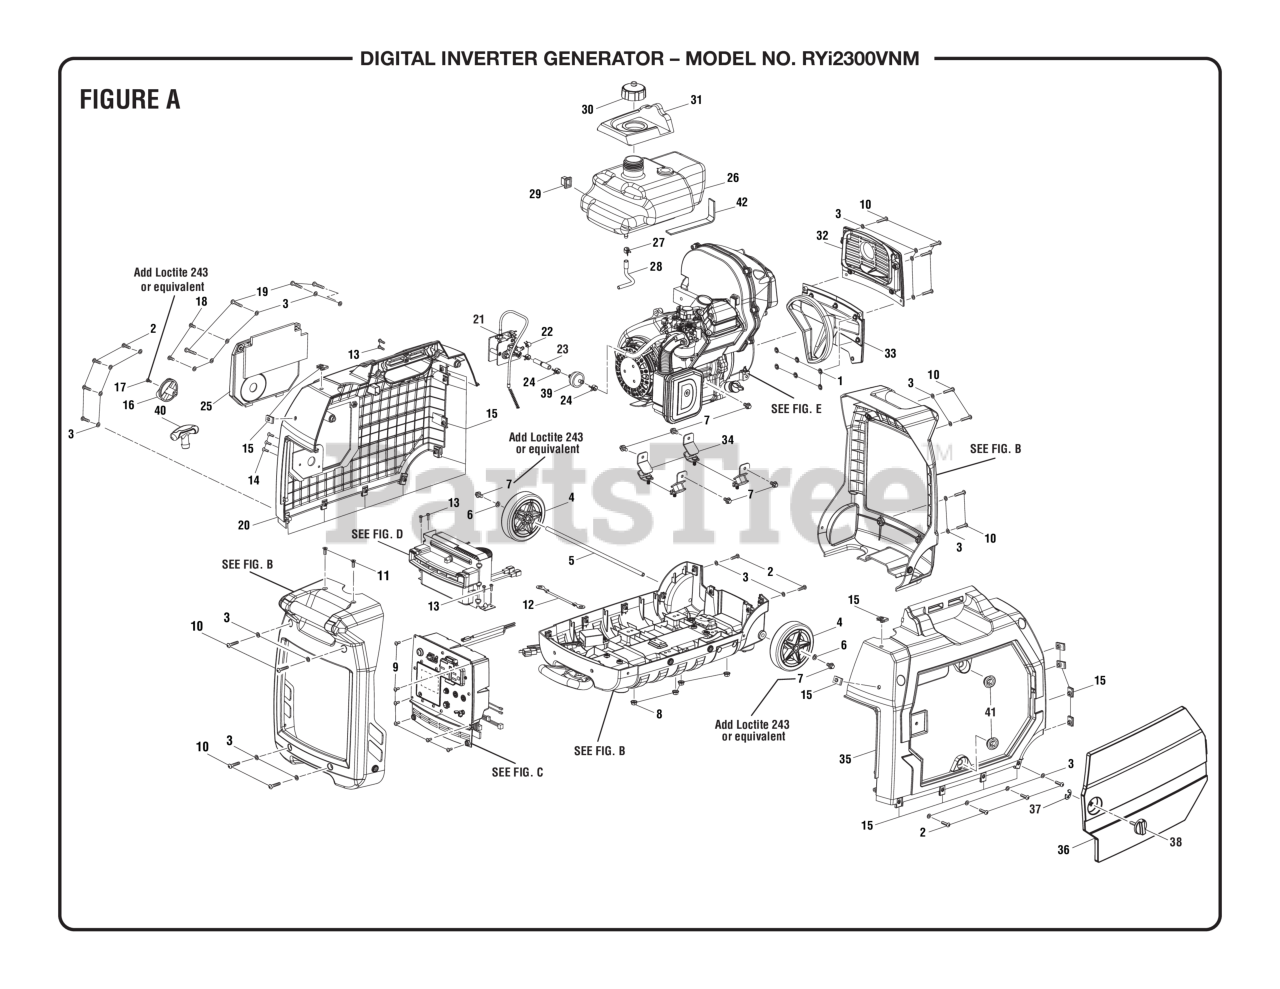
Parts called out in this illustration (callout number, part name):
1	Internal tooth washer (5 mm ID)
2	Screw (M5 x 20 mm, Button Soc. Hd.)
3	Washer (ID5.3 x OD10 x 1t)
6	Lock Washer (1/4 in.)
7	Bolt (M6 x 12 mm, Hex Hd.)
8	Lock Nut (M6)
9	Screw w/Washer (M4 x 10 mm, T20 Torx Button Hd.)
10	Screw (M5 x 25 mm, Button Soc. Hd.)
11	Screw (M5 x 16 mm, Flat Hd.)
12	Ground Wire
13	Screw (M4 x 12 mm, T15 Torx Pan Hd.)
14	Screw (M4 x 16 mm, Flat Hd.)
15	U-Clip (M5)
16	Control Knob
17	Screw (M4 x 10 mm)
18	Screw (M5 x 12 mm, T25 Torx Pan Hd.)
19	Screw (M5 x 30 mm, T25 Torx Pan Hd.)
20	Left Housing Assembly
21	Engine Start/Stop Mechanism Assembly
22	Fuel Line Clamp (3/8 in.)
23	Fuel Hose (4.5 mm and 6 mm)
24	Fuel Hose Clamp (9.5 mm)
25	Starter Cover Assembly
26	Fuel System Assembly
27	Clamp (D10 x 0.8 mm)
28	Fuel Hose (6mm and 4.5 mm)
29	Support (Fuel Tank)
30	Vented Fuel Cap
31	Overspill Guard
32	Upper Exhaust Panel Assembly
33	Lower Exhaust Panel Assembly
34	Engine Isolator (45 Degree)
35	Right Housing Assembly
36	Maintenance Cover Assembly
37	E-Clip (5 mm Shaft)
38	Lock Knob
39	Fuel Filter Inline (1/4 in.)
40	Recoil Handle
42	Rubber Pad
